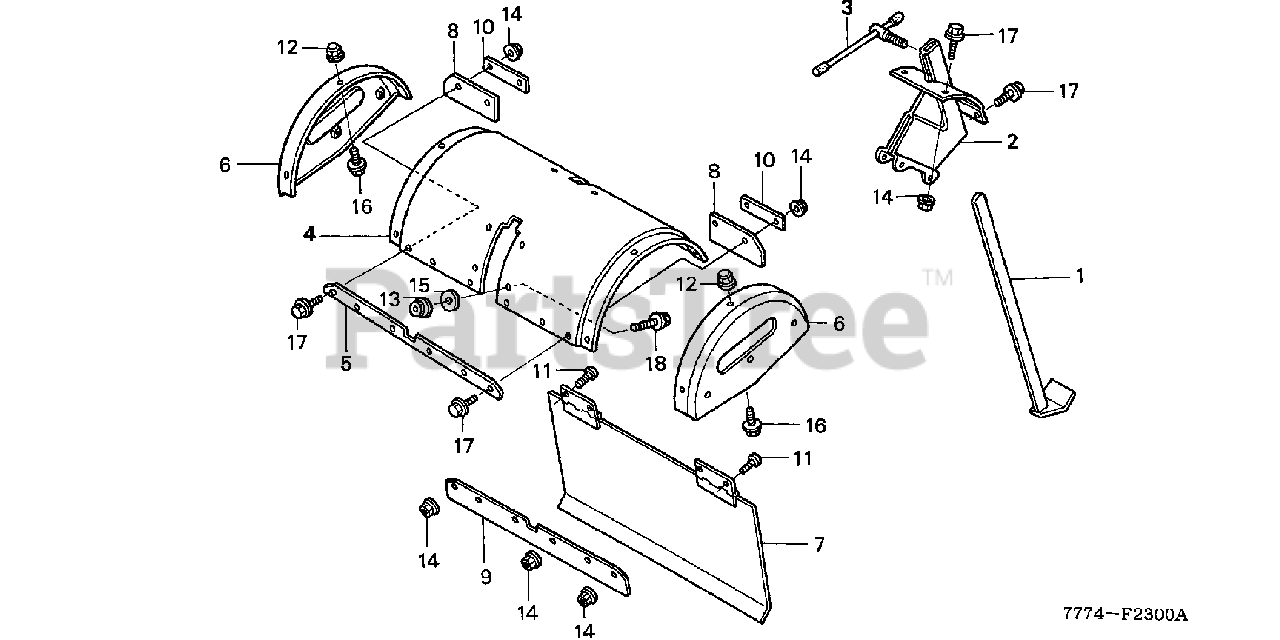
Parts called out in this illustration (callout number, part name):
2	HOLDER, DRAG BAR
3	LEVER, HEIGHT ADJUSTING
4	COVER, ROTOR MAIN *R280* (POWER RED)
5	PLATE, ROTOR COVER
6	COVER, ROTOR SIDE *R280* (POWER RED)
7	SPLASH GUARD, ROTARY CENTER *NH105* (C) (MAT BLACK)
8	SPLASH GUARD, FR. ROTARY
9	STAY, SPLASH GUARD
10	PLATE, SPLASH GUARD SETTING
11	BOLT, SPECIAL (8X16)
12	NUT, FLANGE CAP (8MM)
13	NUT, FLANGE (M8X1.25) (SELF-LOCK)
14	NUT, FLANGE (8MM)
15	WASHER, PLAIN (8MM)
16	BOLT, FLANGE (8X12)
17	BOLT, FLANGE (8X16)
18	BOLT, FLANGE (8X25)
